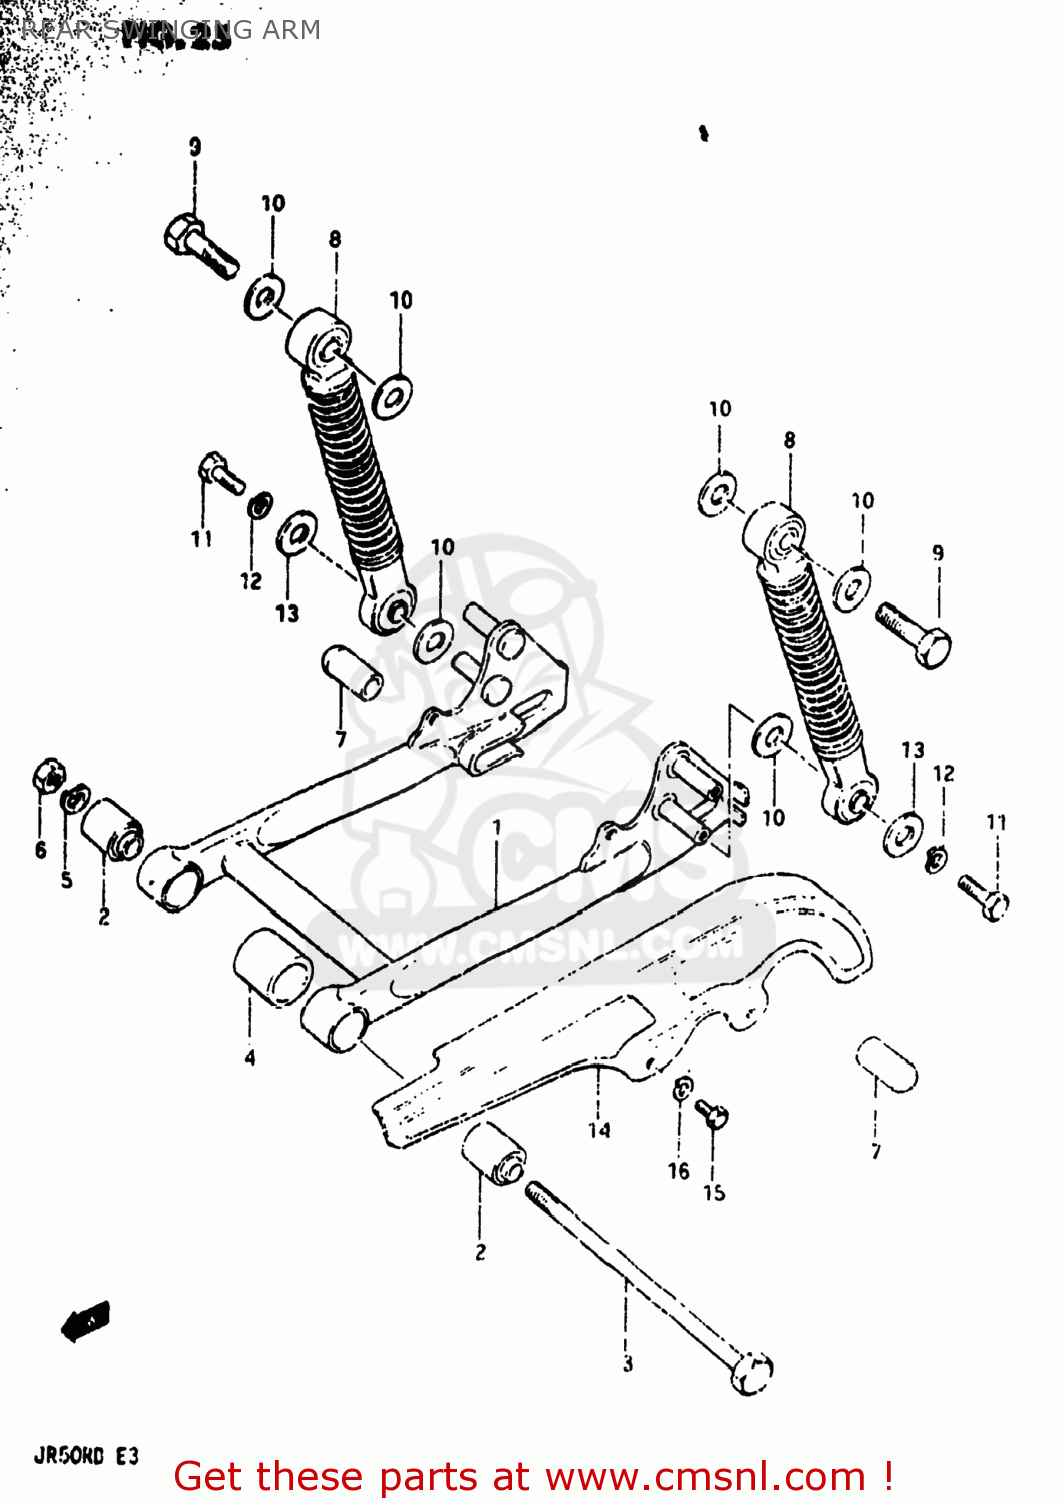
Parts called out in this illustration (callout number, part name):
1	SWING ARM ASSEMBLY,REAR
2	BUSH
3	SHAFT,REAR SWING ARM
4	CUSHION
5	LOCK WASHER
6	NUT
7	CAP,RR SHOCK ABSORBER BOSS
8	ABSORBER ASSY,RR SHOCK
9	BOLT,M10X1.25X
10	WASHER
11	BOLT
12	LOCK WASHER
13	WASHER (6.5X24X1.6)
14	CASE,CHAIN
15	BOLT
16	LOCK WASHER
